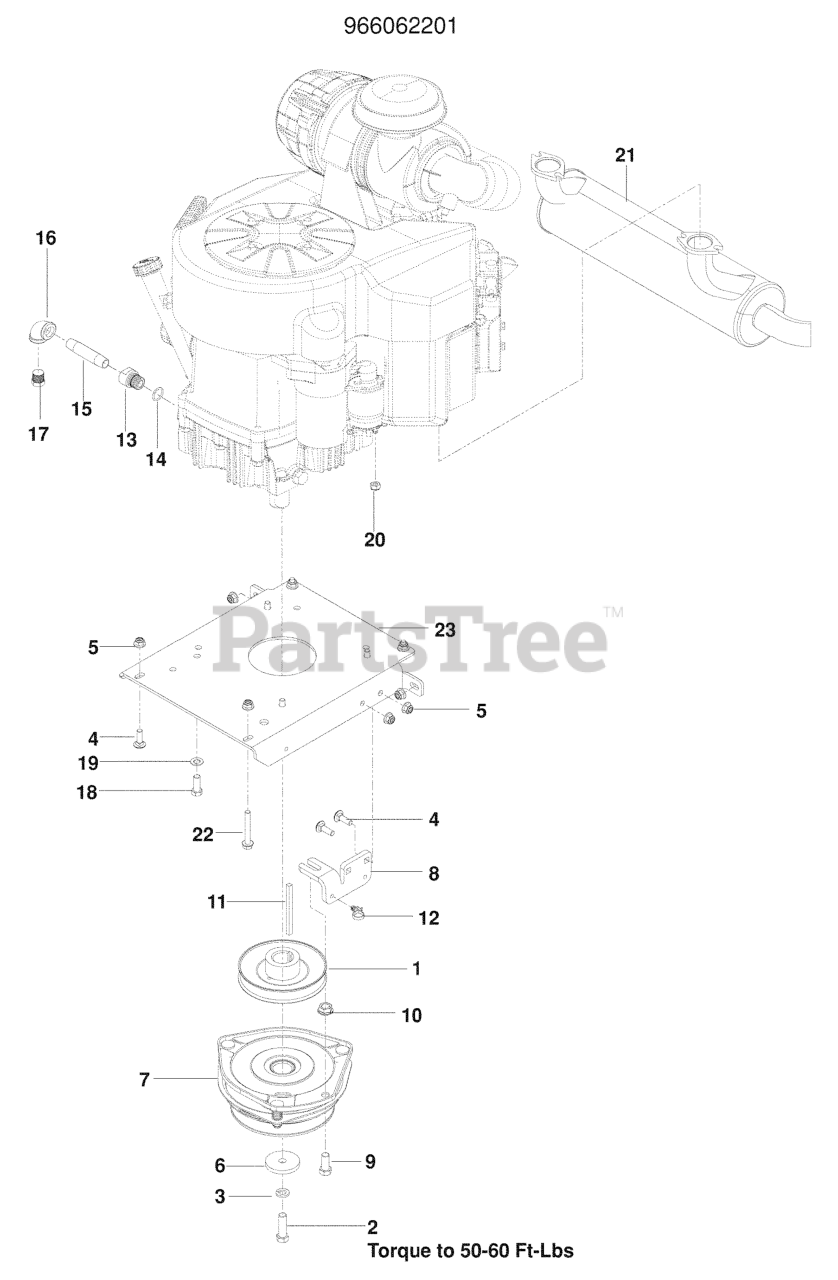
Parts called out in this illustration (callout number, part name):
1	PULLEY, ENGINE
2	HCS 7/16F X 1 1/2
3	WASHER 7/16 LOCK
4	RHSNB 5/16C X 1
5	5/16-18 NYLOC FLANGE NUT
6	BLADE WASHER
7	CLUTCH, GT3.5
8	STOP, CLUTCH, OGURA
9	HCS 7/16-14 X 1 GR 5 ZD
10	NUT 7/16C WHIZ
11	KEY, 1/4 SQ X 3.5
12	TIE WRAP, 8-3/8", W/CLIP
13	ADAPTER, OIL DRAIN
15	PIPE NIPPLE 3/8 X 3
16	90 DEG.ELBOW 3/8NPT
17	PLUG, DRAIN 3/8 NPTF
18	HCS 3/8-16X1.GRD.5.ZD
19	WASHER, 3/8 DISC SPRING SPEC
20	NUT M8-1.25 TOP NYL GR10 ZD
21	MUFFLER, 29HP KAW FX751V-850V
22	HHFS 5/16-18 X 2.25 GD 5
23	PLATE.ENGINE.BLACK
